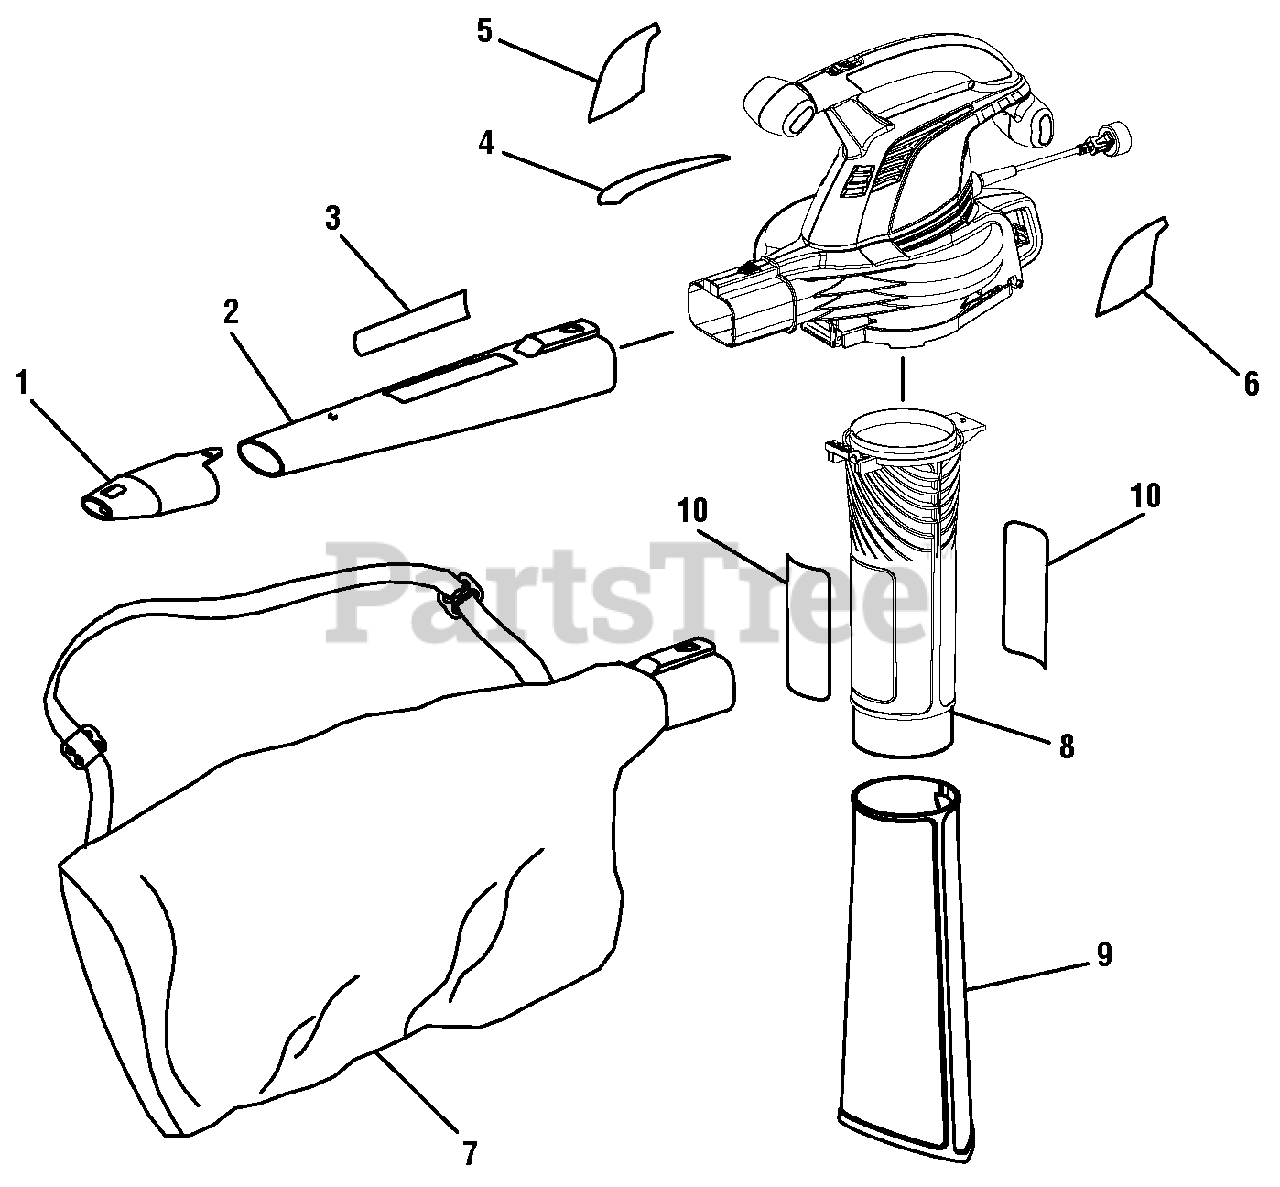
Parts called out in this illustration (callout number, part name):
1	High Velocity Nozzle
2	Blower Tube
3	Logo Label (Blower Tube)
7	Vacuum Bag
8	Upper Vacuum Tube
9	Lower Vacuum Tube
10	Logo Label (Upper Vacuum Tube)
